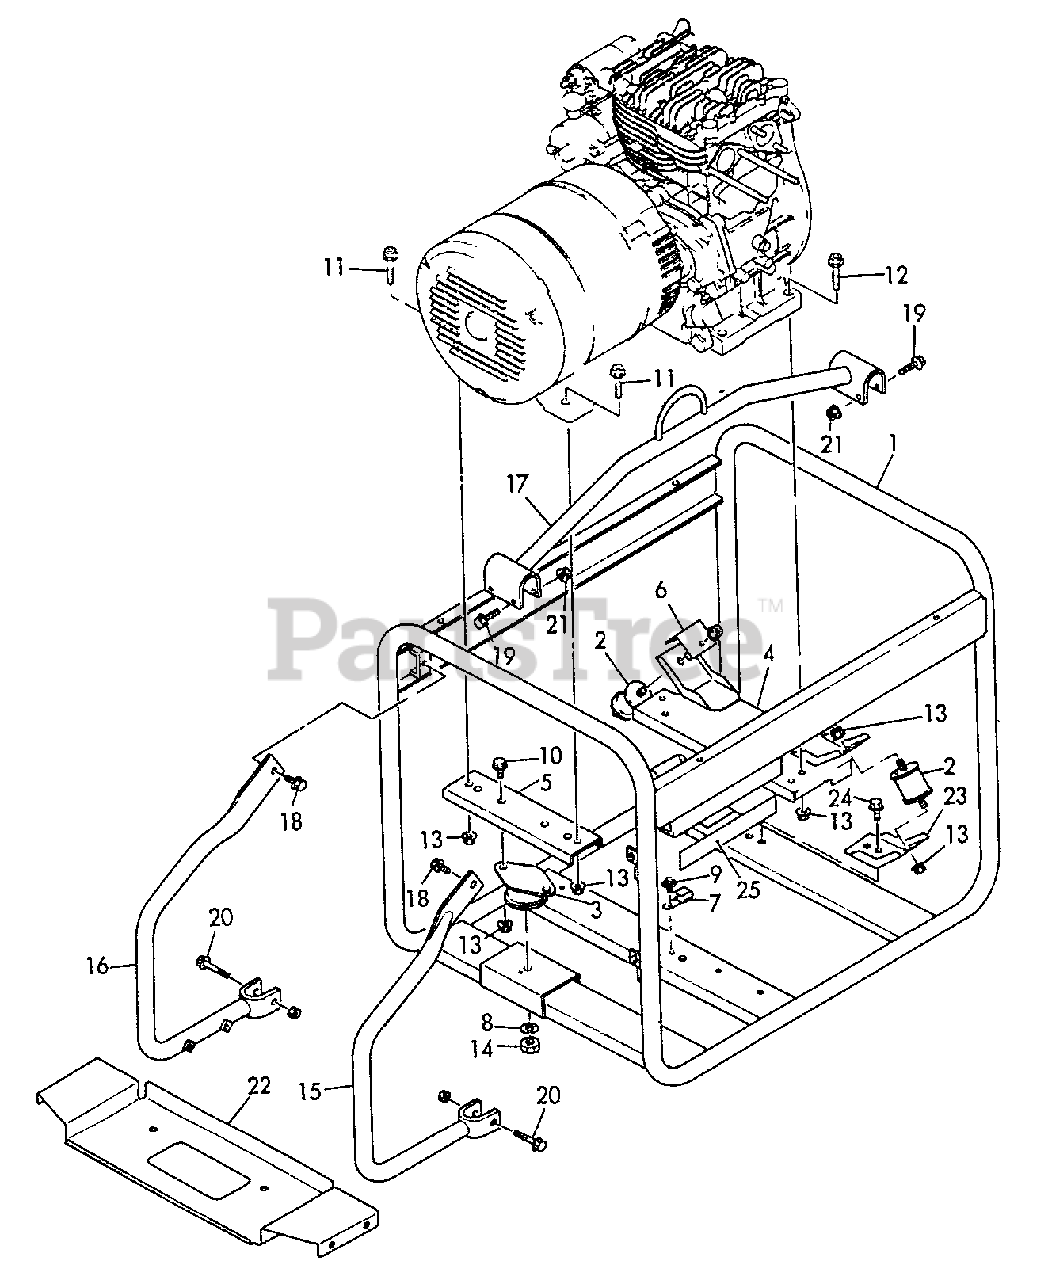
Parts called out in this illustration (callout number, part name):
1	FRAME
2	DAMPER, FRONT
3	DAMPER, REAR
4	STAY, DAMPER
5	STAY, REAR DAMPER
6	COVER, DAMPER
7	CLAMP
8	LOCKWASHER - 10
9	BOLT - 6×8 -- PLATED
10	BOLT - 8×20 -- PLATED
11	BOLT - 8×30 -- PLATED
12	BOLT - 8×38 -- PLATED
13	U-NUT M8
14	NUT - 10
15	SIDE FRAME, RIGHT
16	SIDE FRAME, LEFT
18	BOLT - 6×12 -- PLATED
19	BOLT - 6×30
20	BOLT - 6×40
21	U-NUT M6
22	BRACKET, BATTERY
23	DAMPER STAY, LOWER
24	BOLT - 8×16 -- PLATED
25	SHEET, FRAME
